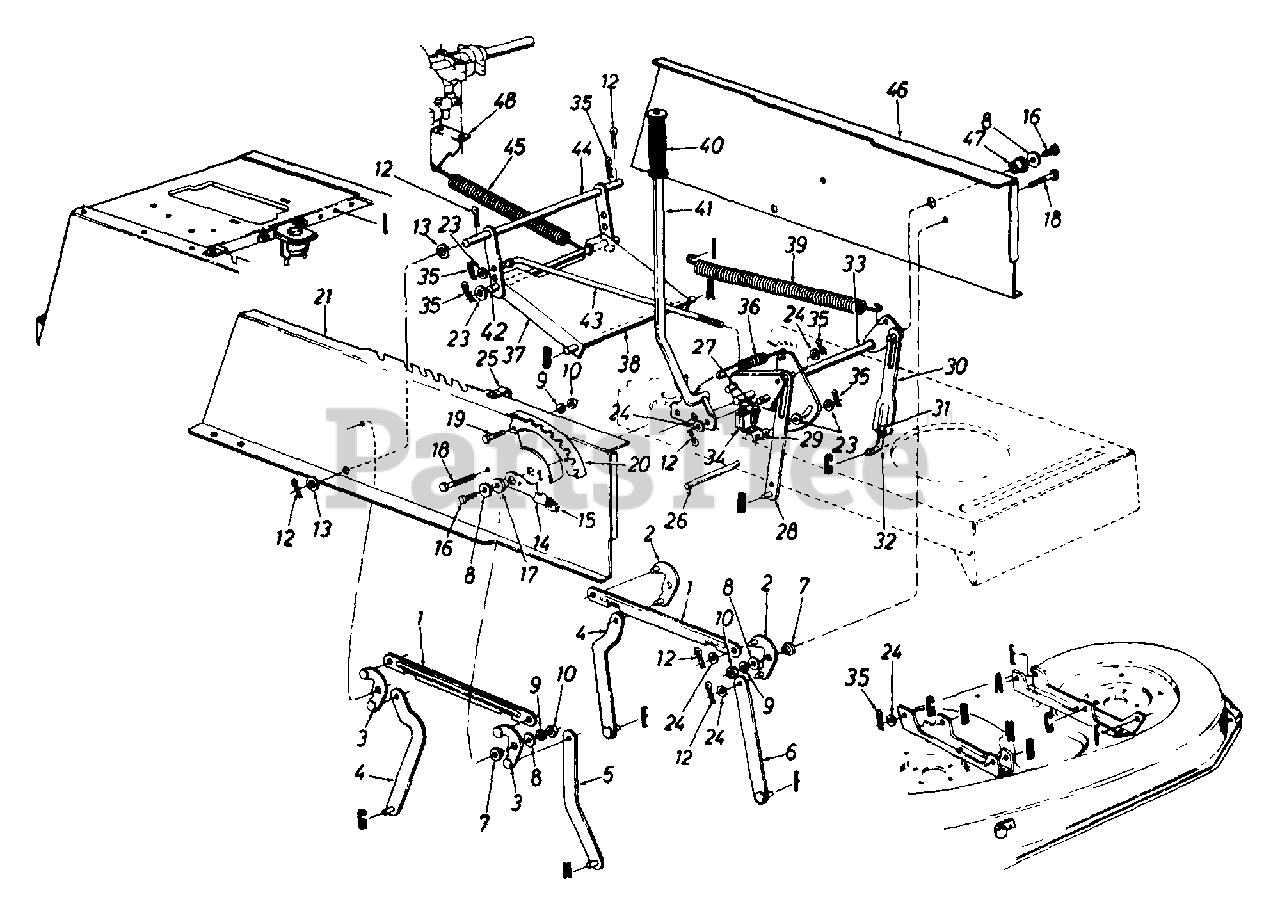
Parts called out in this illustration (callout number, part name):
1	Connecting Rod
2	Pivot Link Ass'y.- L.H.
3	Pivot Link Ass'y.- R.H.
7	Shld. Spacer.318" I.D.
8	Fl-Wash..344" I.D. x.62" O.D.
9	L-Wash. 5/16" I.D.
10	Hex Nut 5/16-18 Thd.
12	Cotter Pin 1/8" Dia.
13	Fl-Wash..635" I.D. x 1.0" O.D.
14	Deck Lift - Down Stop
15	Knobs
16	Hex Wash. TT-Tap Scr. 5/16-18 x .75" Lg.
17	Flange Brg..63" I.D.
18	Hex Wash. Hd. Scr. 5/16-18x .875" Lg.
19	Hex Bolt 5/16-18 x .75" Lg.
20	Index Brkt.
21	Upper Frame - R.H.
23	Fl-Wash..385" I.D. x .87" O.D.
24	Fl-Wash..531" I.D. x.93" O.D.
25	Clamp
26	Running Board Rod
27	Hex Wash. Hd. Tap Scr.
31	Hex Nut 1/2-20 Thd. (Gr. 5)
32	Lift Link Adjuster
35	Inter. Cotter Pin 3/8" Dia.
36	Extension Spring
37	Stabilizer Bracket
38	Shaft 1/2" Dia. x 10.28" Lg.
39	Extension Spring
40	Grip (Lift Handle)
41	Deck Lift Handle Ass'y.
42	Shaft 3/8" Dia. x 9.34" Lg.
43	Disengagement Rod
44	Stabilizer Shaft Ass'y.
45	Extension Spring 7.58" Lg.
46	Upper Frame - L.H.
47	Flange Brg..632" I.D.
48	Spring Retainer Brkt.
